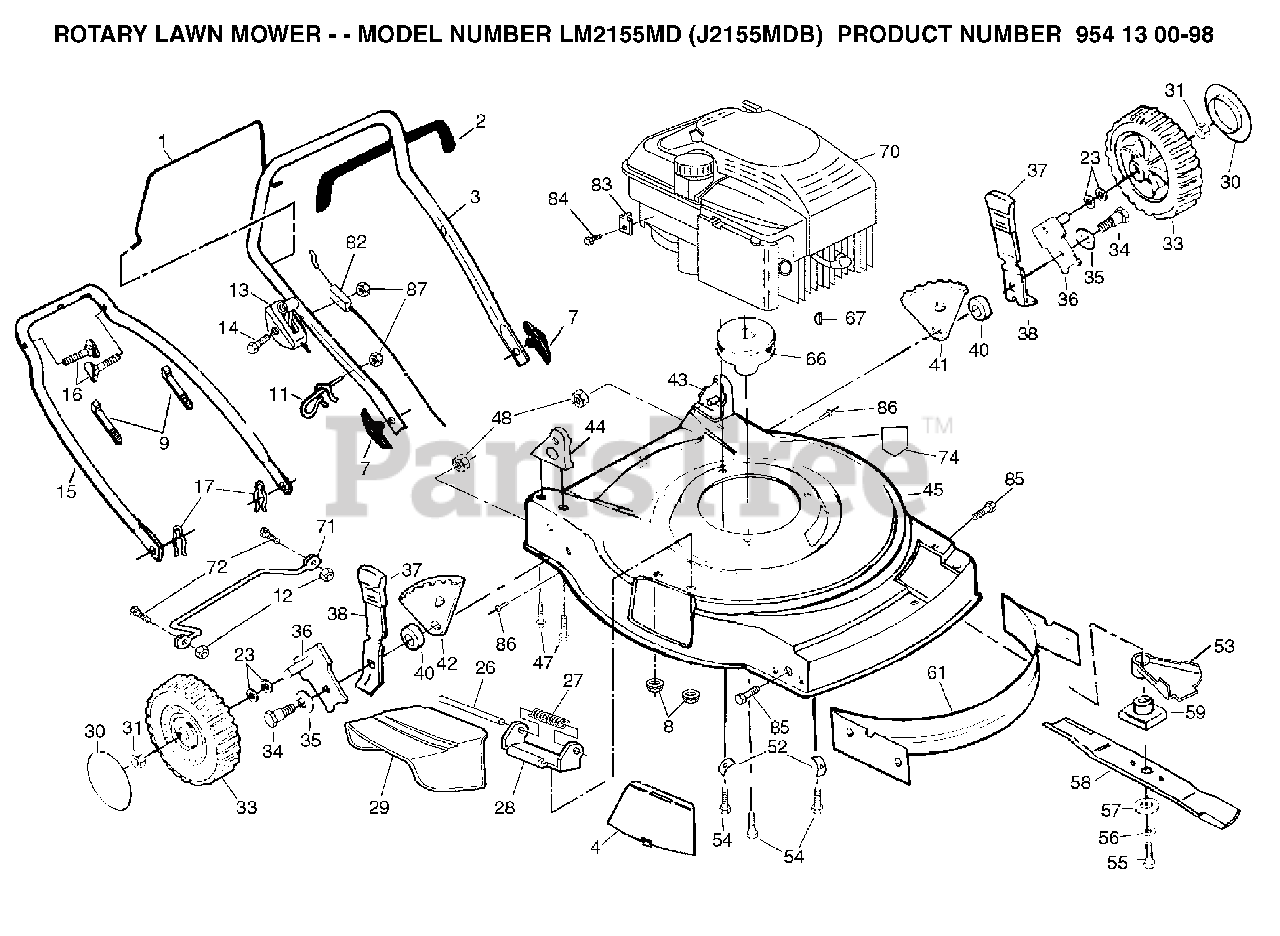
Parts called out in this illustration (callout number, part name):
1	CONTROL BAR ORANGE
2	GRIP.HANDLE.FOAM
7	HANDLE KNOB
8	LOCKNUT
9	TIE GUIDE
11	ROPE, GUIDE
13	THROTTLE CONTROL
14	SCREW 1/4-20 X 2.12
15	LOWER HANDLE
16	HANDLE BOLT
17	HAIRPIN COTTER
20	WAVE WASHER
26	ROD.HINGE.COMBI-C
27	SPRING PM
28	BRACKET PM
31	HEX FLANGE LOCKNT
33	WHEEL.8X2.PR.LP.RAD.GREY
34	BOLT
35	BELLEVILLE WASHER
36	AXLE ARM
37	SELECTOR KNOB
40	RP SPACER HT ADJ
43	HANDLE BRACKET ASM. LH
44	HANDLE BRACKET ASM. RH
47	SCREW 5/16-18
48	LOCKNUT PM
53	SHIELD.DEBRIS.21.RWGD.EZ
54	BOLT 3/8-16X1-1/8
55	SCREW, HEX HD 3/8-24 X 1-3/8
56	LOCKWASHER
57	WASHER,HARDEN
59	RP BLADE ADAPTOR
66	ENGINE.PULLEY.FWG
67	HI PRO KEY PM
74	DECAL.INTERNATIONL.CUTFINGER
82	ENGINE ZONE CONTROL
83	CABLE CLAMP(ENGINE)
84	SCREW.HEX.HEAD.WASHER.10-16
86	RIVET BLIND
87	NUT
